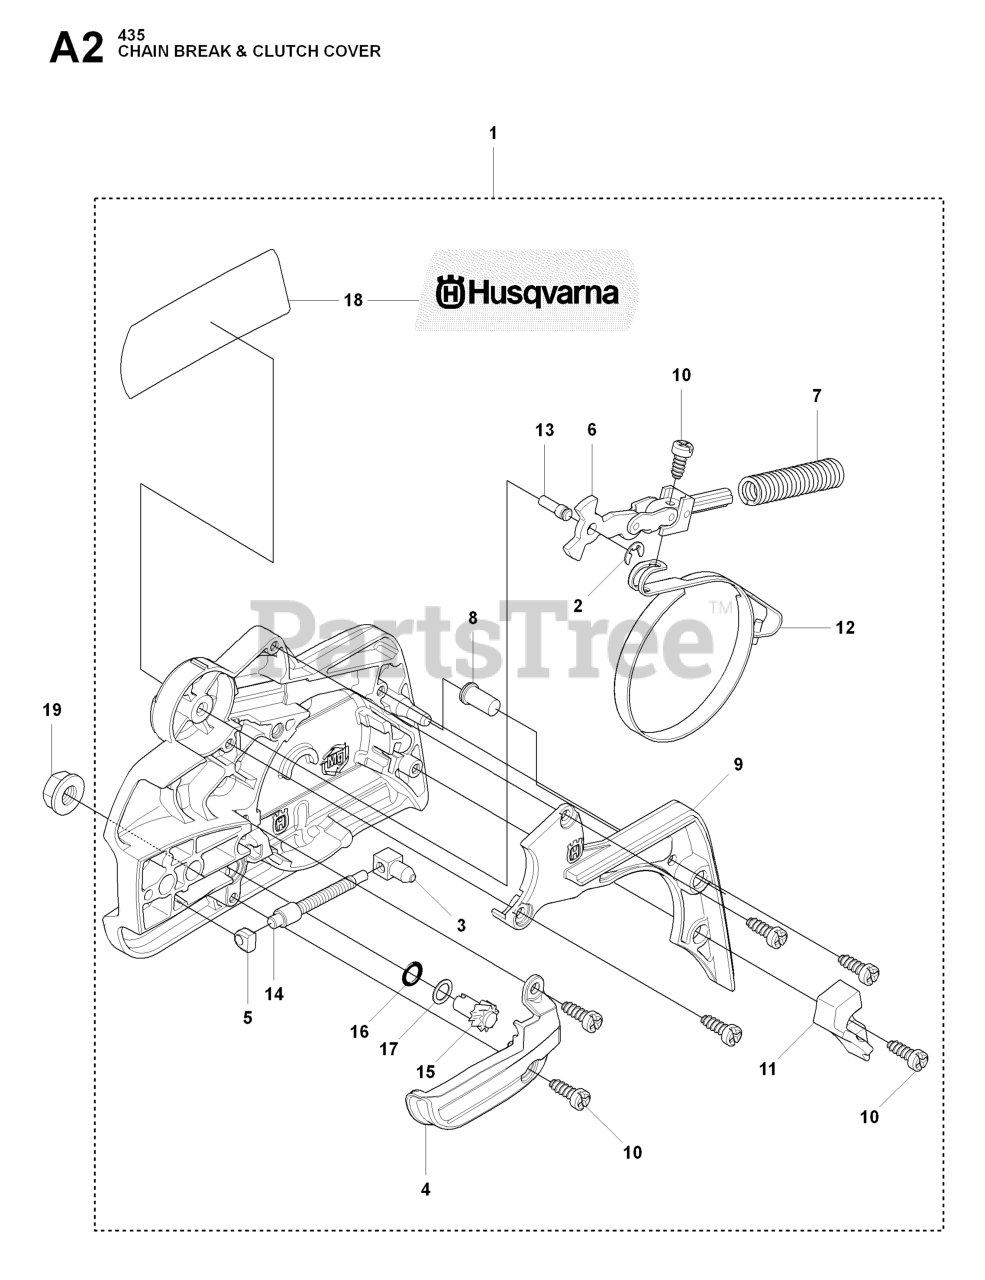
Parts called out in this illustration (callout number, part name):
1	CLUTCH COVER ASSY
2	E-RING 4
3	PAWL
4	CHAIN GUIDE
5	SLEEVE
6	JOINT
7	BRAKE SPRING
8	SLEEVE
9	COVER
10	SCREW
11	WEAR PROTECTION
12	BRAKE BAND ASSY
13	PIN
14	SCREW
15	WORM WHEEL
16	O-RING
17	WASHER
18	LABEL 400 SERIES
19	NUT M8 FLANGE
